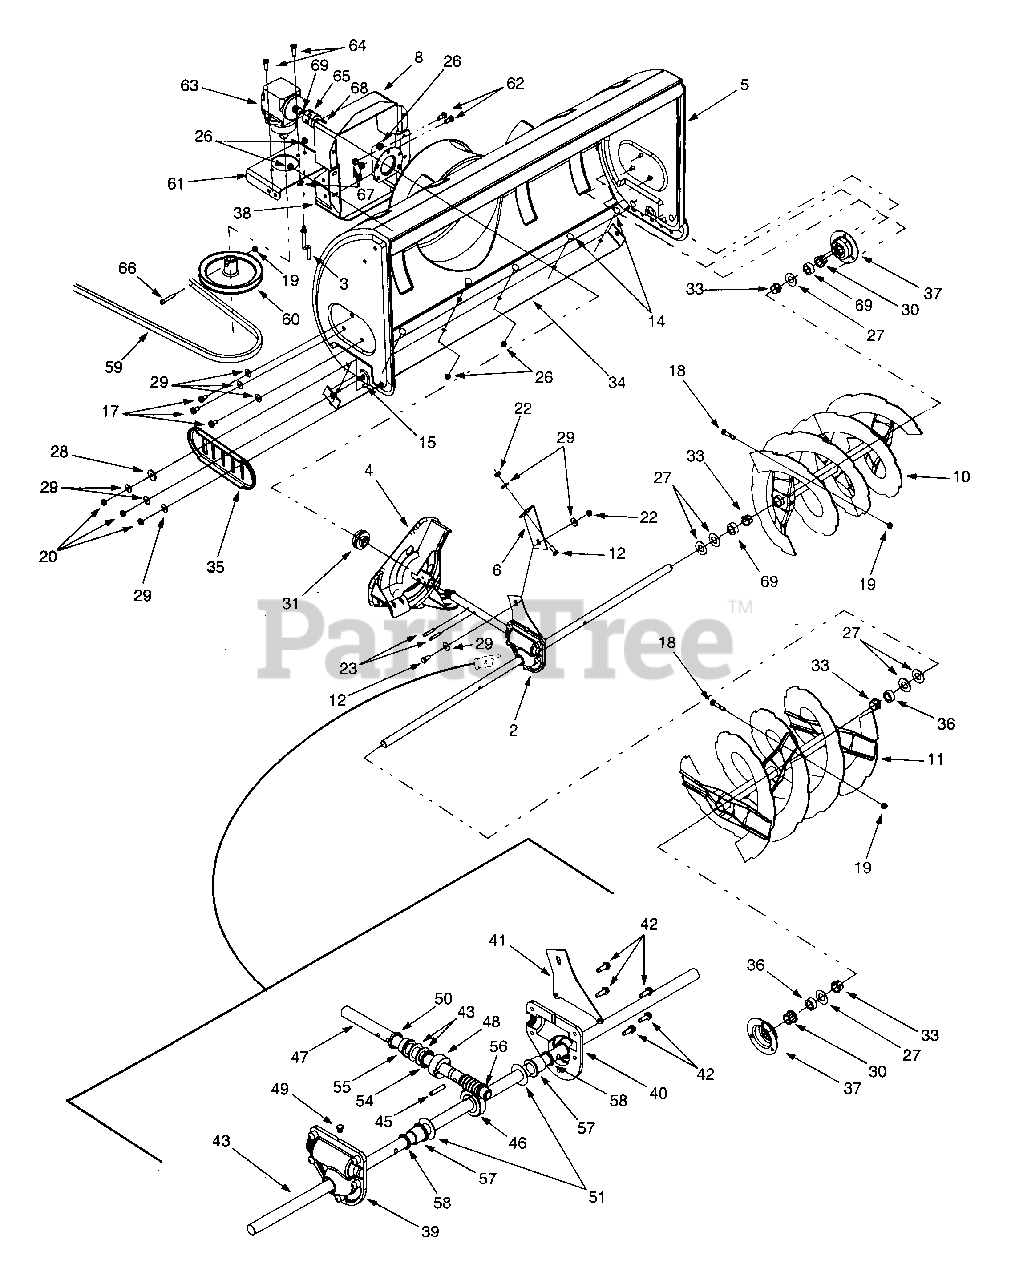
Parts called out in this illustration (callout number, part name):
1	Bearing Housing, 1.85 ID
2	Auger Gear Case
3	Belt Keeper Rod
4	Impeller Assembly, 12"
10	LH Spiral Auger, 40"
11	RH Spiral Auger, 40"
12	Hex Cap Screw, 5/16-24 x .75
13	Carriage Screw, 1/4-20 x .5
14	Carriage Bolt, 5/16-18 x .62
15	Splined Carriage Screw, 5/16-18 x 1.0
16	Carriage Bolt, 5/16-18 x .75
17	Self Tapping Screw, 5/16-18 x .625
18	Shear Bolt, 5/16-18 x 1.5
19	Hex Lock Nut, 5/16-18
20	Hex Nut, 5/16-18
21	Hex Flange Lock Nut, 1/4-20
22	Hex Nut, 5/16-24
23	Spirol Pin, 1/4 x 1-1/2
24	Spirol Pin, .125 x .812
25	Adapter Chute
26	Flange Lock Nut, 5/16-18
27	Flat Washer, .76 x 1.49 x .06
28	Flat Washer, .344 x 1.125 x .12
29	Bell Washer, .340 x .872
30	Hex Flange Bearing, .75 ID
31	Flange Ball Bearing, .75 x 1.85
32	Plastic Bushing, .38
33	Flange Bushing, .80 x .91
34	Skid Plate Bracket, 42"
35	Slide Shoe
36	Spacer, .75 x .125 x .5
37	Hex Bearing Housing, 1.0
38	Skid Plate
39	RH Reducer Housing
40	LH Reducer Housing
42	Self Tapping Screw, 1/4-20 x .75
43	Spiral Axle, 41.5"
44	Hi-Pro Key, 3/16 x 5/8
45	Spring Spirol Pin, .25 x 1.25
46	Worm Gear, 20-tooth
47	Worm Shaft
48	Thrust Collar
49	Grease Plug
50	Grease Seal
51	Flat Washer, .76 x 1.5 x .030
52	Flat Washer, .508 x 1.0 x .020
53	Thrust Washer, .75 x 1.25 x .0615
54	Thrust Bearing, .75 x 1.25 x .078
55	Flange Bearing, .75 x 1.0 x .59
56	Flange Bearing, .503 x .75
57	Flange Bearing, .754 x 1.0 x .925
58	Grease Seal
59	Lower V-belt
60	Drive Pulley, 7"
61	Drive Mounting Bracket
62	Hex Cap Screw, 3/8-16 x .75
63	Right Angle Drive
64	Hex Cap Screw, 3/8-16 x 1.0
65	Coupling
66	Socket Head Cap Screw, 5/16-18 x 1.75
67	Flange Lock Nut, 3/8-16
68	Square Key, 3/16 x .75
69	Hi-pro Key, 3/16 x .75
70	Bearing Housing, 1.85 ID
